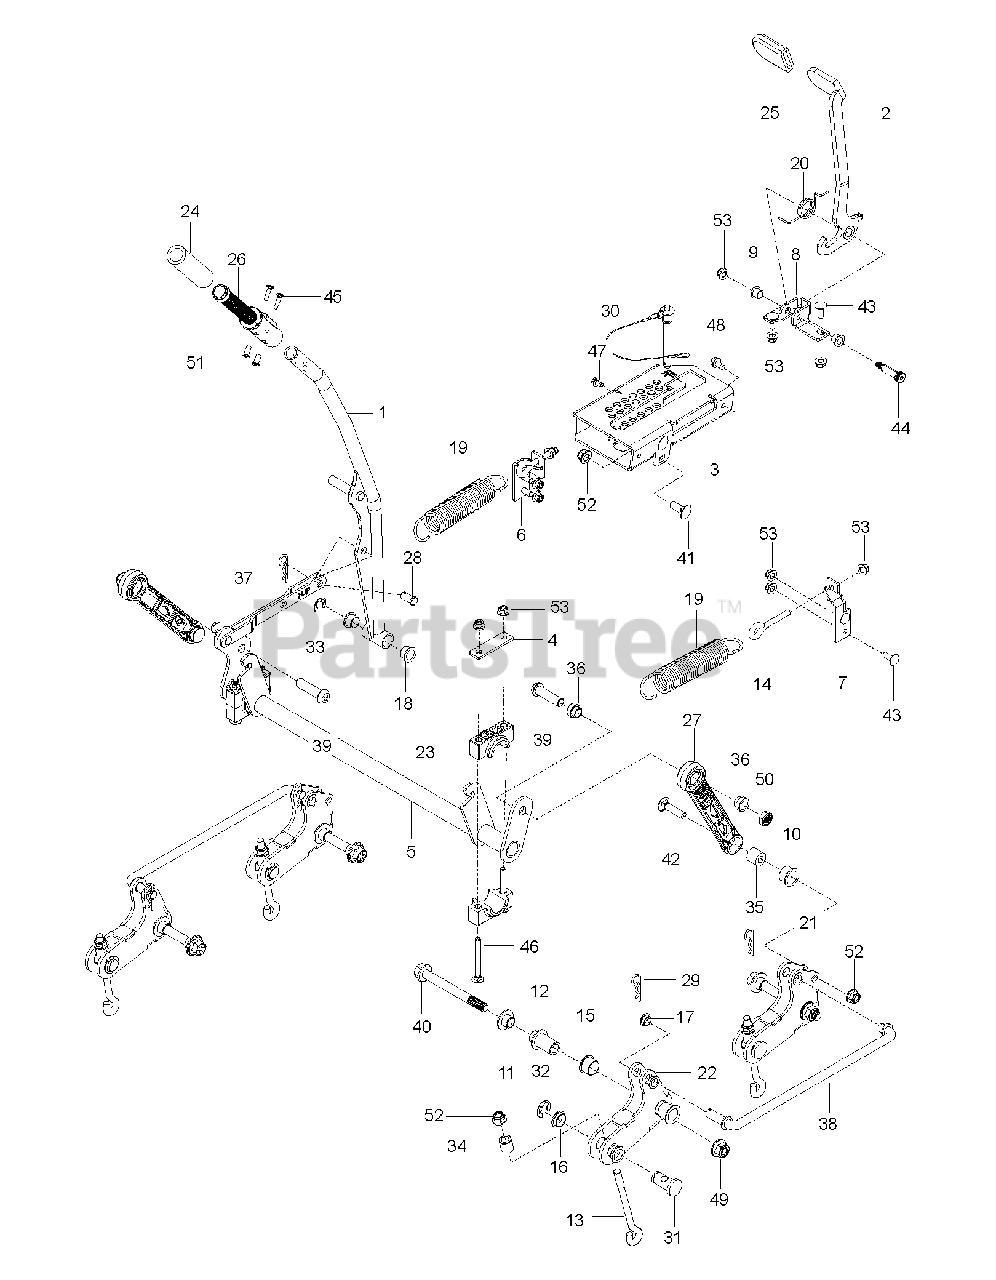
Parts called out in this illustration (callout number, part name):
1	LEVER ASSY WELDMENT; DECK LIFT
2	LATCH WELDMENT; TRANSPORT MODE
3	PLATE DECK HEIGHT SELECTION X6
4	Plate, Pillow Block
5	SHAFT WELDMENT; DECK LIFT X431
6	BRACKET SPRING ANCHOR LH X431
7	BRACKET SPRING ANCHOR RH X431
8	BRACKET TRANSPORT MODE X431 E-
9	BUSHING FLANGED PLASTIC; RFI-0
10	BUSHING NYLON 1 X 3/4
11	BUSHING STANDON BELLCRANK PIVO
12	BUSHING STANDON BELLCRANK PIVO
13	EYEBOLT, DECK LIFT
15	BEARING FLANGED;PLASTIC 1" ID
16	BEARING FLANGED;PLASTIC 7/8" I
17	BEARING FLANGED;PLASTIC 5/8" I
18	BEARING, FLANGE
19	SPRING EXTENSION; STAND-ON DEC
20	SPRING TORSION; TRANSPORT MODE
21	BELLCRANK STANDON REAR WELDMEN
22	BELLCRANK STANDON FRONT WELDME
23	BLOCK, PILLOW
24	GRIP FOAM; DECK LIFT HANDLE
25	GRIP TRANSPORT MODE
26	HANDLE DECK LIFT LEVER ARM HUS
27	LINKAGE ASSY; CONNECTING; DECK
28	Clevis Pin, 1/2 X 1
29	HAIRPIN #4
30	PIN.PUSH.BUTTON.DETENT..5X3.5
31	PIN STANDON DECK LIFT TRUNNION
32	E-CLIP 7/8" SHAFT
33	RING E-CLIP 3/4" ID
34	SPACER, EYEBOLT
35	SPACER LINKAGE PIVOT E-COAT BL
36	SPACER, STRUT
37	STRAP
38	ROD.CONNECT.BELLCRANK.STANDON
39	BOLT CUP HEAD SQUARE NECK 5/3-
40	BOLT HEXAGON HEAD WITH FLANGE
41	Cup Head Square Neck Bolt, 1/2-
42	Cup Head Square Neck Bolt, 1/2-
43	RHSNB 3/8C X 1
44	BOLT HEXAGON SOCKET HEAD, SHOU
45	Roundhead Squareneck Bolt, 1/4-20 X 1, Grade 5
47	SCR 5/16-18 X 1/2 SELFTAP ZN
48	SCREW LT.3/8-46X5/8
49	NUT 5/8-11 FLG NYLOC ZD
50	NUT.HH.THIN.NYL.5/8-11 GR5
51	NUT HEXAGON SOCKET CAP 1/4-20"
52	NUT, 1/2-13 HEX FLG NYLOC ZD
53	NUT 3/8-16 HEX FLG NYLOC ZD
